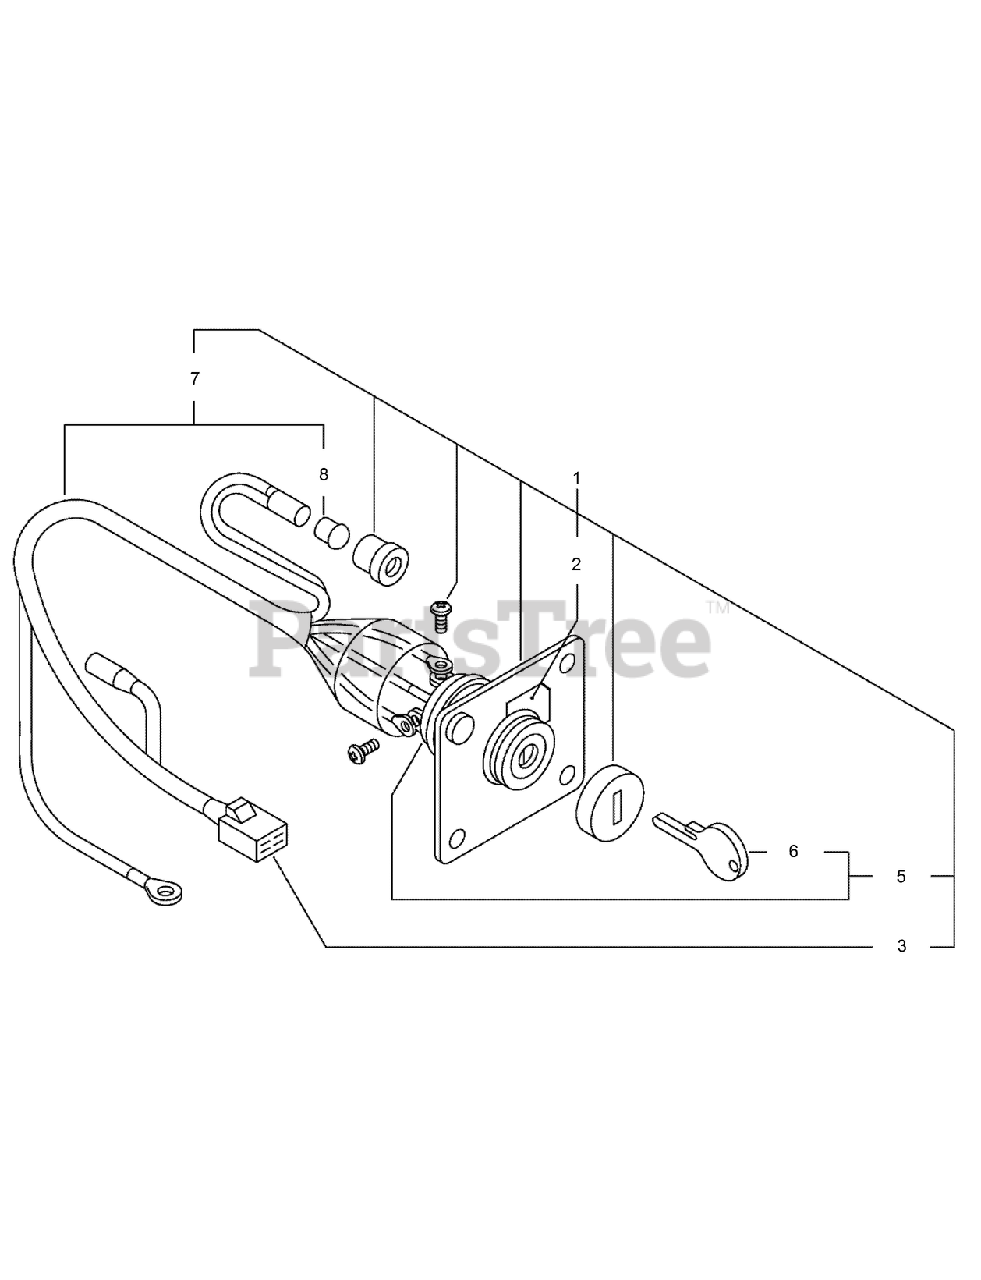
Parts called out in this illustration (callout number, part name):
1	SWITCH PANEL ASM
2	LABEL-START SWITCH
3	COUPLER
5	SWITCH AND KEY ASM
6	KEY-SWITCH
7	HARNESS-WIRE
